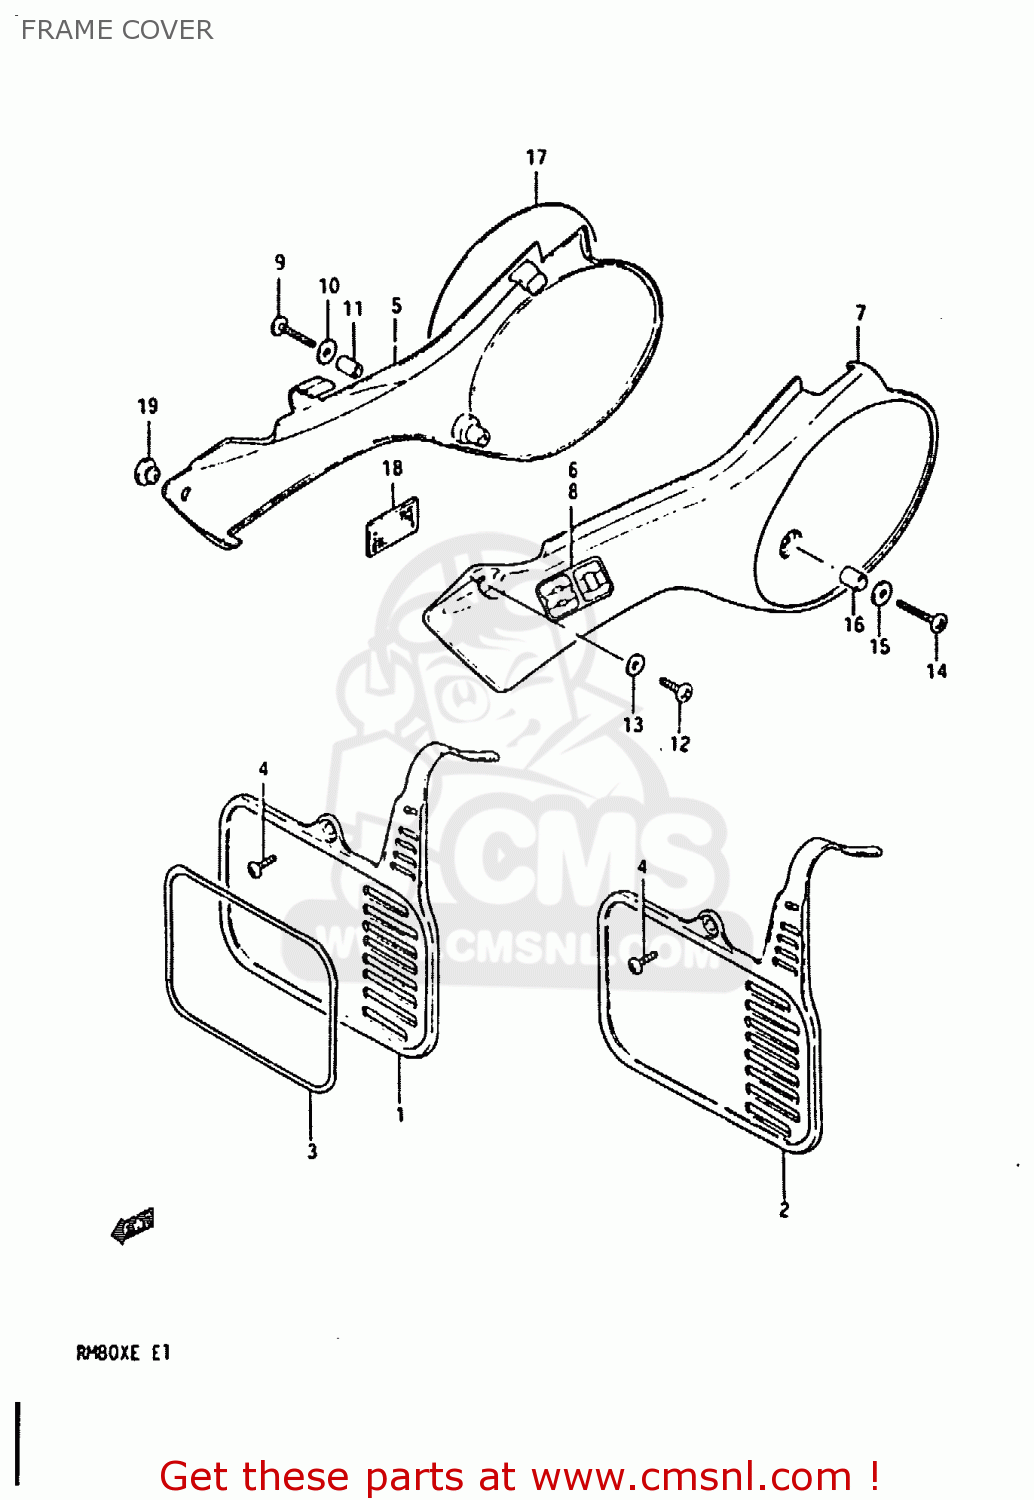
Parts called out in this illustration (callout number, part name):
1	PLATE,FR NUMBER
2	PLATE,NUMBER,FRONT
3	TAPE SET,FRONT NUMBER PLATE
4	SCREW M5X12 DIN 7985/N
5	COVER,FRAME,RIGHT
6	EMBLEM (80)
7	COVER,FRAME,LEFT
8	EMBLEM (80)
9	SCREW
10	WASHER (6.5X18X1.6)
11	SPACER(6.8X10X24.2)
12	SCREW
13	WASHER
14	SCREW
15	WASHER (6.5X18X1.6)
16	SPACER (6.4X9X20)
17	EMBLEM,FRAME COVER
18	HEAT SHIELD,FRAME COVER
19	CUSHION
